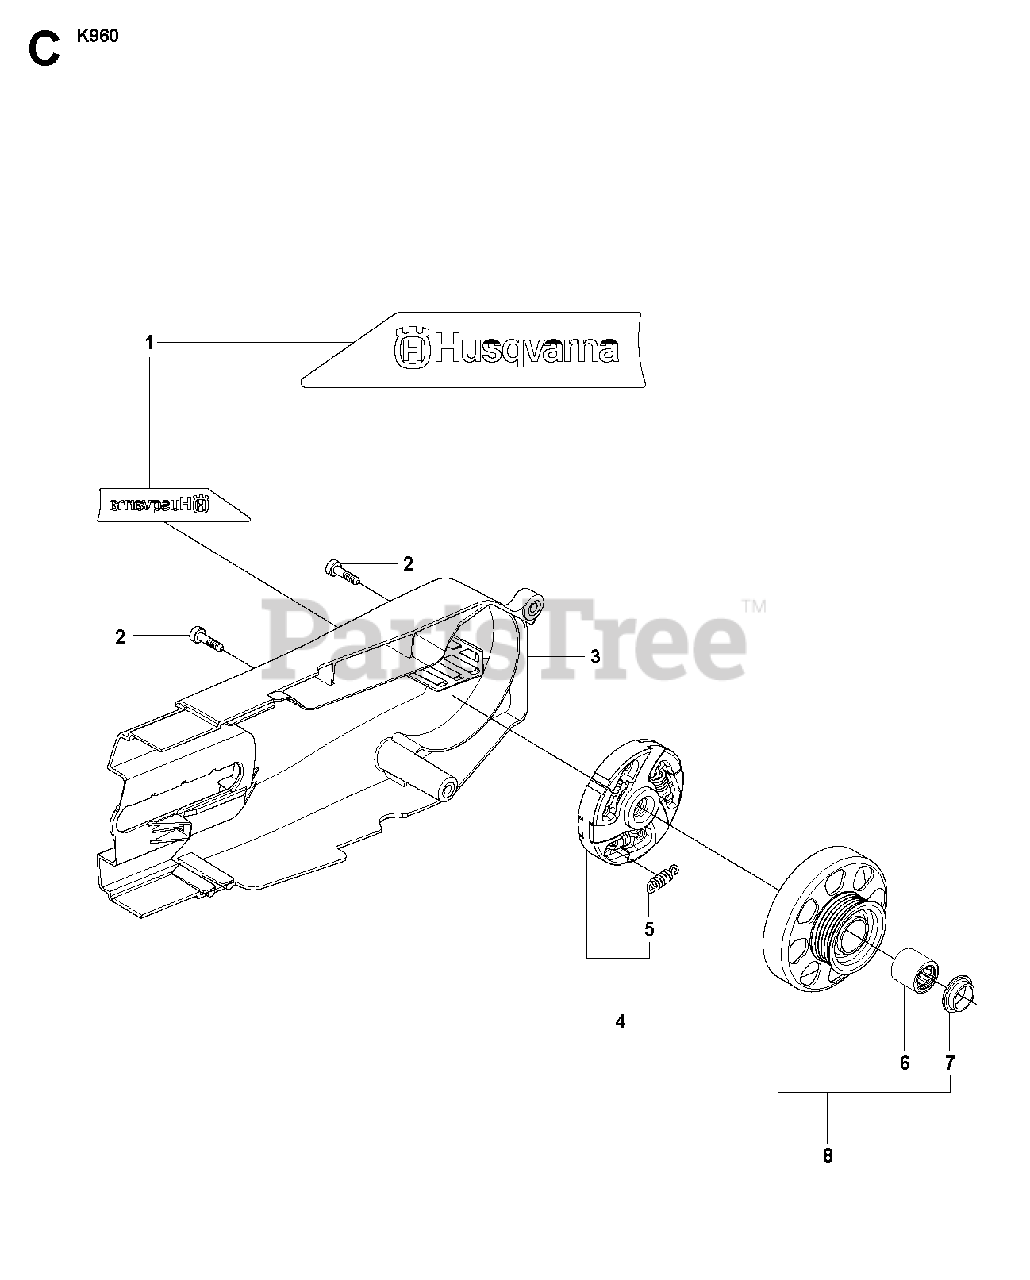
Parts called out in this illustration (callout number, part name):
2	SCREW ITXSCM
3	BELT GUARD
4	CLUTCH ASSYIncl. 5
5	CLUTCH SPRING
6	NEEDLE BEARING
8	DRIVING PULLEY ASSY"12"", 14"". Incl. 6, 7"
8	DRIVING PULLEY ASSY"16"". Incl. 6, 7"
